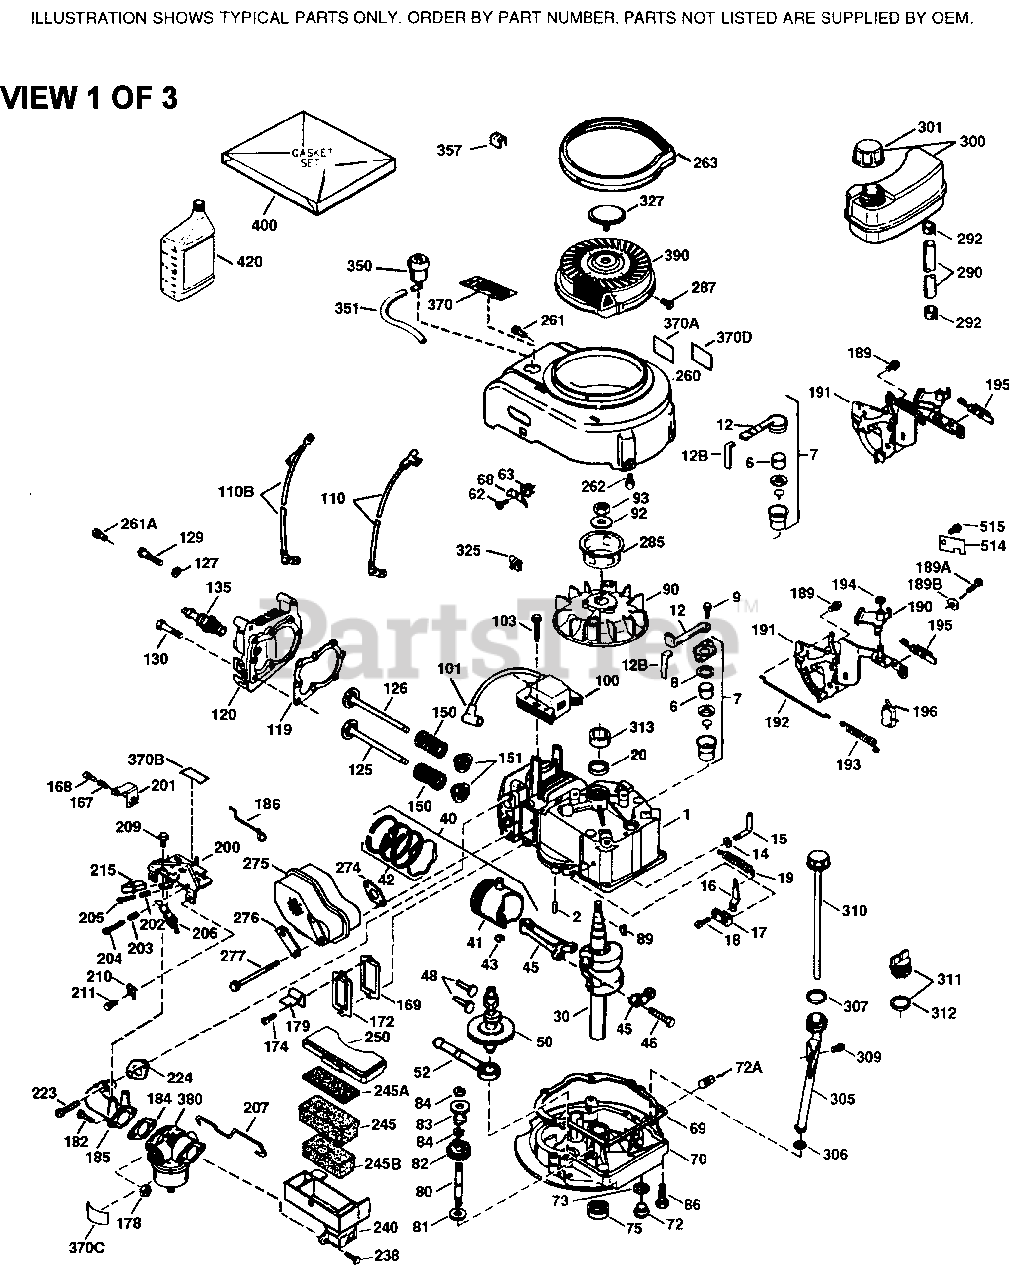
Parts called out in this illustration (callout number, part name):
1	"Cylinder (Incl. 2 & 20)
2	Dowel Pin
6	Breather Element
7	Breather Ass'y. (Incl. 6, 8, 9, & 12)
8	* Breather Gasket
9	Screw, 10-24 x 9/16"
12	Breather Tube
14	Flat Washer
15	Governor Rod (Incl. 14)
16	Governor Lever
17	Governor Lever Clamp
18	Screw, 8-32 x 5/16"
19	Extension Spring
20	Oil Seal
30	Crankshaft
40	Piston, Pin & Ring Set (Std.)
40	Piston, Pin & Ring Set (.010" OS)
40	Piston, Pin & Ring Set (.020" OS)
41	Piston & Pin Ass'y. (Std.) (Incl. 43)
41	Piston & Pin Ass'y. (.010" OS) Incl. 43
41	Piston & Pin Ass'y. (.020" OS) Incl. 43
42	Ring Set (Std.)
42	Ring Set (.010" OS)
42	Ring Set (.020" OS)
43	Piston Pin Retaining Ring
45	Connecting Rod Ass'y. (Incl. 46)
46	Connecting Rod Bolt
48	Valve Lifter
50	Camshaft (MCR)
52	Oil Pump Ass'y.
69	Mounting Flange Gasket
70	Mounting Flange (Incl. 72 thru 83)
72	Oil Drain Plug
75	Oil Seal
80	Governor Shaft
82	Governor Gear Ass'y. (Incl. 81)
83	Governor Spool
86	Screw, 1/4-20 x 1-1/4"
89	Flywheel Key (also available in Packa ged Part #740007B)
90	Flywheel
92	Belleville Washer
93	Flywheel Nut
100	Solid State Ignition
101	Spark Plug Cover
103	Screw, Torx T-15, 10-24 x 1"
110	Ground Wire
119	* Cylinder Head Gasket
120	Cylinder Head
125	Exhaust Valve (Std.) (Incl. 151)
125	Exhaust Valve (1/32" OS) (Incl. 151)
126	Intake Valve (Std.) (Incl. 151)
126	Exhaust Valve (1/32" OS) (Incl. 151)
130	Screw, 5/16-18 x 1-1/2"
135	Resistor Spark Plug (RJ19LM) also ava ilable in Packaged Part #740081
150	Valve Spring
151	Valve Spring Cap
169	* Valve Cover Gasket
172	Valve Cover
174	Screw, 10-24 x 1/2"
178	Nut & Lock Washer 1/4-28
179	Retainer Clip
182	Screw, 1/4-28 x 7/8"
184	* Carburetor To Intake Pipe Gasket
185	Intake Pipe (Incl. 224)
186	Governor Link
200	Control Bracket (Incl. 202 thru 206)
202	Compression Spring
203	Compression Spring
204	Screw, 5-40 x 7/16"
205	Screw, 6-32 x 21/32"
206	Terminal
207	Throttle Link
209	Screw, 10-24 x 9/16"
210	Conduit Clip
211	Screw, 10-32 x 3/8"
223	Screw, 1/4-20 x 1"
224	* Intake Pipe Gasket
238	Screw, 10-32 x 5/8"
240	Air Cleaner Body
245	Air Filter (Poly) (also available in Packaged Part #740023B)
250	Air Cleaner Cover
260	Blower Housing
261	Screw, 10-24 x 9/16"
262	Screw, 1/4-20 x 1/2"
275	Muffler
276	Locking Plate
277	Screw, 1/4-20 x 2-31/32"
285	Starter Cup
287	Screw, 8-32 x 21/64"
290	Fuel Line
292	Fuel Line Clamp
300	Fuel Tank (Incl. 292 & 301)
301	Fuel Cap (Red 1-1/2" ID) also availab le in Packaged Part #740005B
305	Oil Fill Tube
306	* "O" Ring
307	"O" Ring
309	Screw, 10-32 x 1/2"
310	Dipstick
327	Starter Plug
370	Instruction Decal
370A	Primer Decal
380	Carburetor (Incl. 184)
390	Rewind Starter
400	* Gasket Set (Incl. items marked PK in notes). Incl. Part #'s 26756 (1),272 34A (1), 33554A (1), 33735 (1),34265 (1), 34338 (1), 34690A (1)
420	SAE 30 4-Cycle Engine Oil (Quart)
